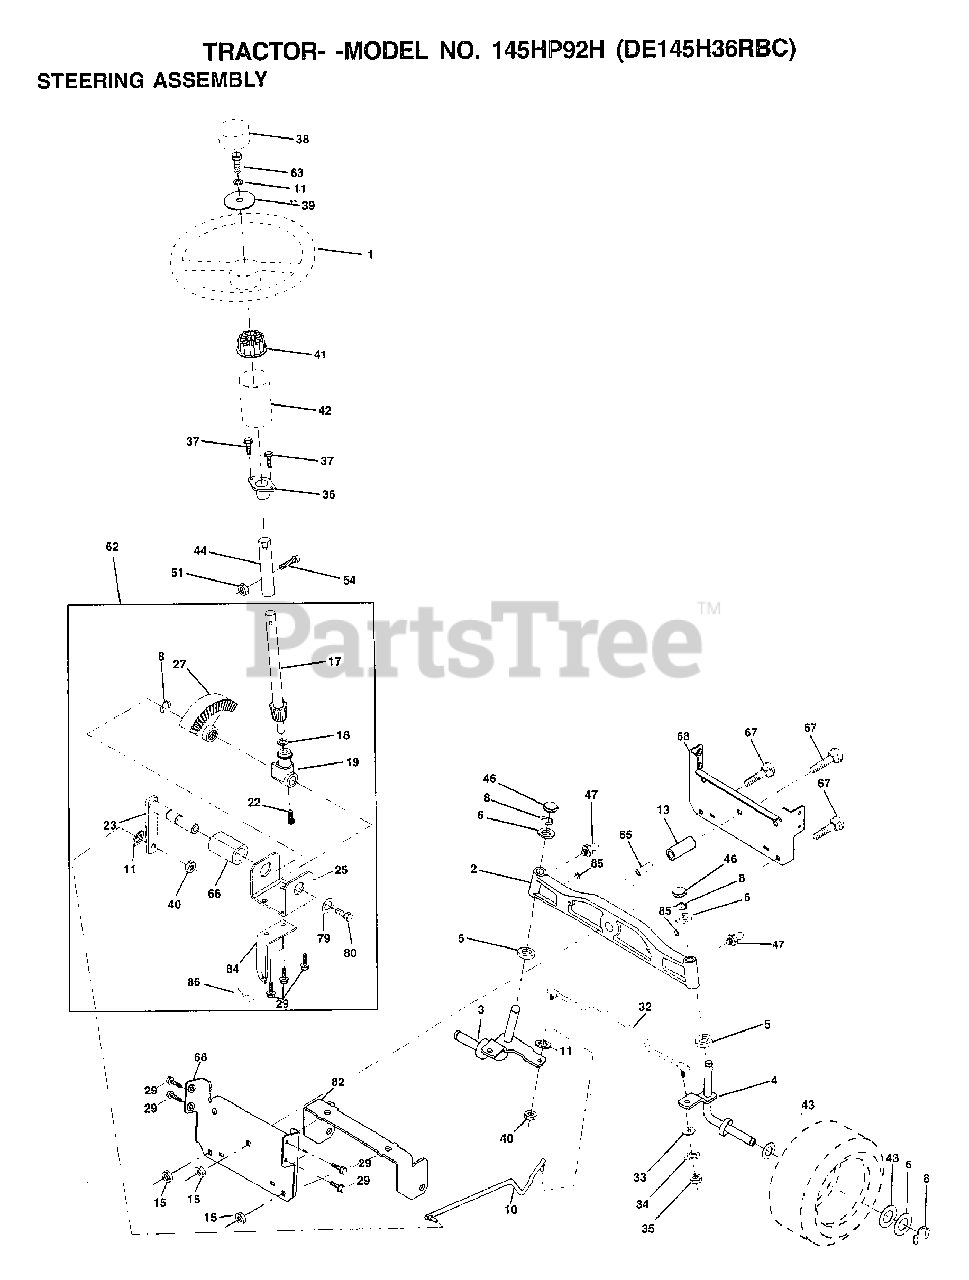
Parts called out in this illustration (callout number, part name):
2	AXLE ASM CAST IRON LT
3	SPINDLE ASM
4	SPINDLE ASM
5	WASHER .T
6	WASHER
8	RING
10	LINK DRAG
11	LOCKWASHER
13	SPACER BEARING
15	NUT.HXFLG.LOCK.
17	SHAFT ASM STEERIN
18	THRUST WASHER
19	SUPPORT.SHAFT.STEER
22	SCREW.HX.WSH.HD
23	SHAFT.ASM.PITMAN
25	BRKT-STEERING
27	GEAR SECTOR
29	SCREW
32	TIE ROD
33	WASHER M
34	LOCKWASHER
35	NUT.LOCK.5/16-24
36	BUSHING.STEERING
37	"SCREW-TT,10-32 FL"
38	CAP WHEEL STEER
39	WASHER
40	GRIPCO NUT
41	ADAPTER LT
42	BOOT.STEERING.DASH.P/L
43	WASHER
44	EXT SHAFT STEERIN
46	CAP
47	ZERK M
51	NUT
54	BOLT
62	KIT.STEER.ASM
63	BOLT
65	"SPACER BRCAE,AXLE"
66	"BEARING-ARM,PITMA"
67	BOLT RDHD 3/8-16
68	BRACE AXLE
79	WASHER
80	BOLT.HX.NYLON3/8-16X3/
82	BRKT SUSP CHASSIS FRT
84	BRACKET CABLE CLUTCH CHASSIS
85	XMAS TREE FASTNER
86	RETAINER SPRING
